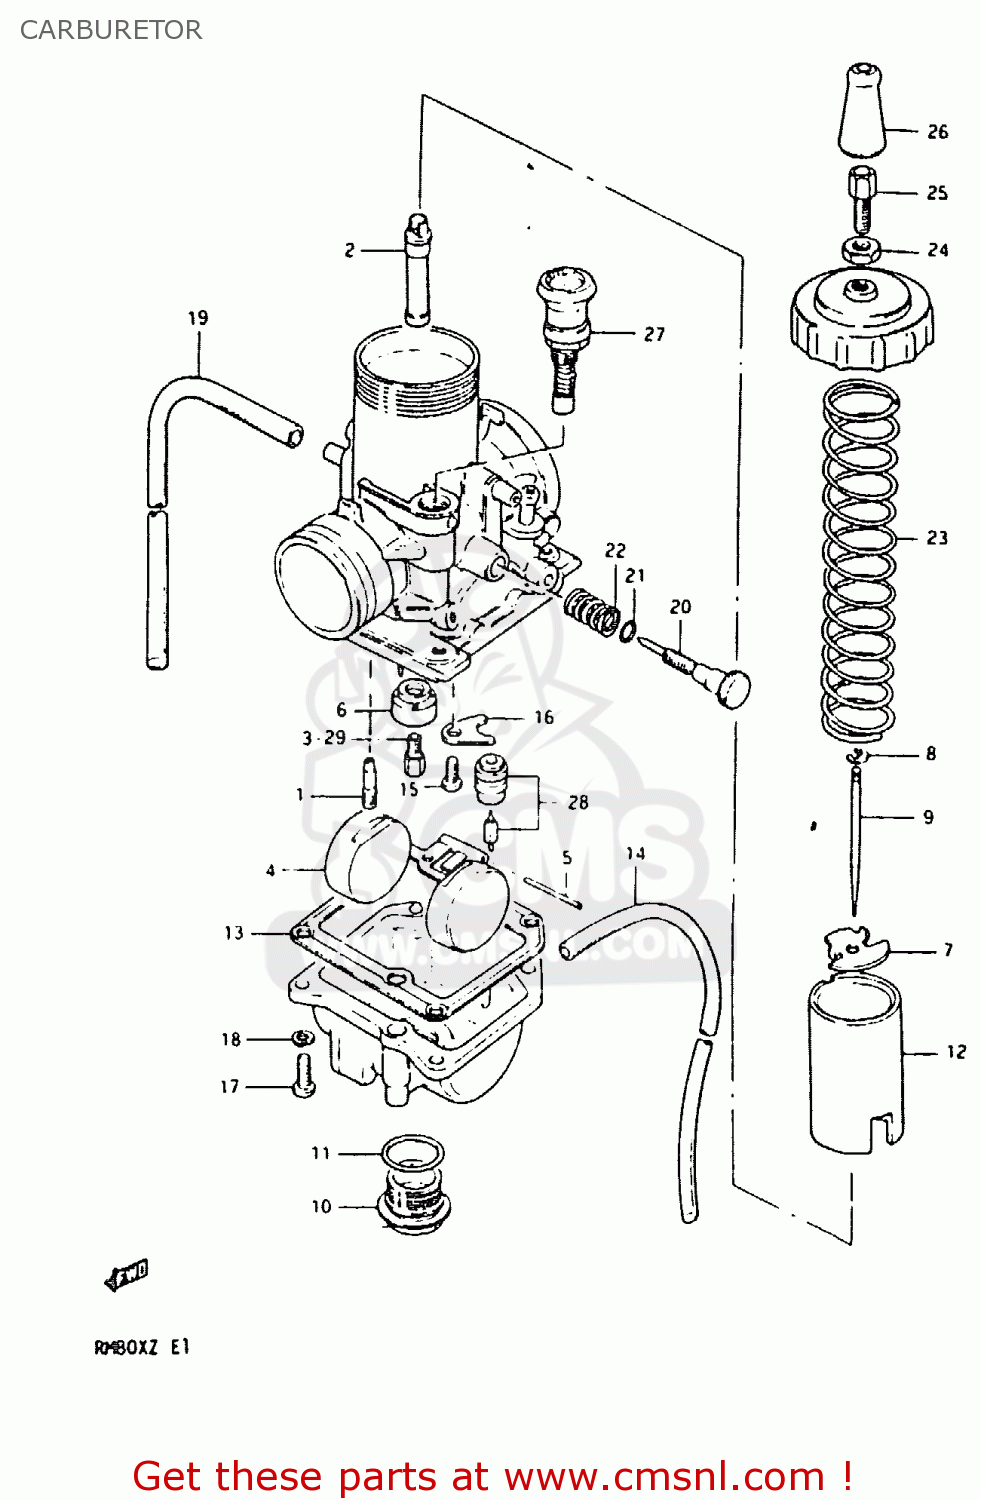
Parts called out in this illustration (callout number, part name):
1	JET,PILOT(45)
2	JET,NEEDLE
3	JET
4	FLOAT
5	PIN,FLOAT
6	RING
7	PLATE,THROTTLE VALVE
8	CLIP
9	NEEDLE,JET(5DP39-4)
10	PLUG
11	O RING
12	VALVE,THROTTLE
13	GASKET,FLOAT CHAMBER (NAS)
14	HOSE
15	SCREW
16	PLATE
17	SCREW
18	LOCK WASHER
19	HOSE
20	ADJUSTER
21	O RING
22	SPRING
23	SPRING,THROTTLE VALVE
24	NUT
25	ADJUSTER,CABLE
26	CAP,RUBBER
27	VALVE ASSEMBLY,STARTER
28	VALVE ASSEMBLY,NEEDLE
29	JET
